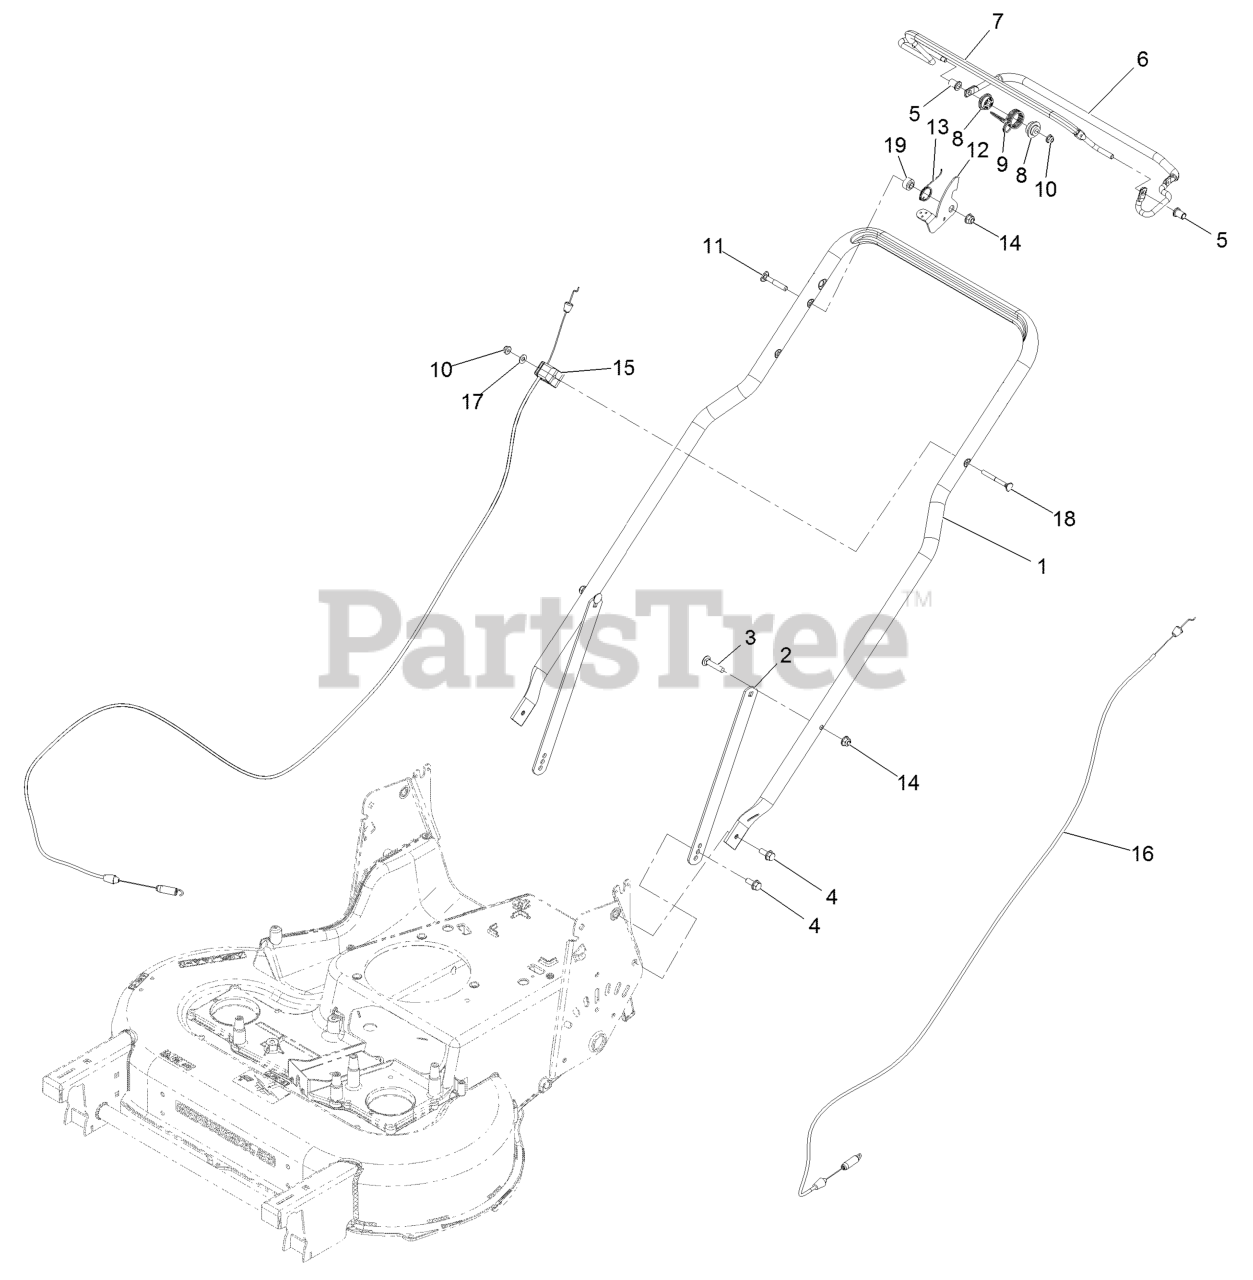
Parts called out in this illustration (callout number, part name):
2	SUPPORT-HANDLE
3	BOLT-CARR
4	SCREW-HHF
5	BUSHING-HANDLEBAR
6	BAIL-DRIVE COATED
8	BUSHING-SPRING, PIVOT
9	SPRING-RETURN, BBC
12	LEVER-BBC
13	SPRING-LEVER, BBC
14	NUT-HF, NI
16	CABLE-TRACTION
17	Washer-Flat
18	SCREW-HANDLE
19	BUSHING-STEPPED
